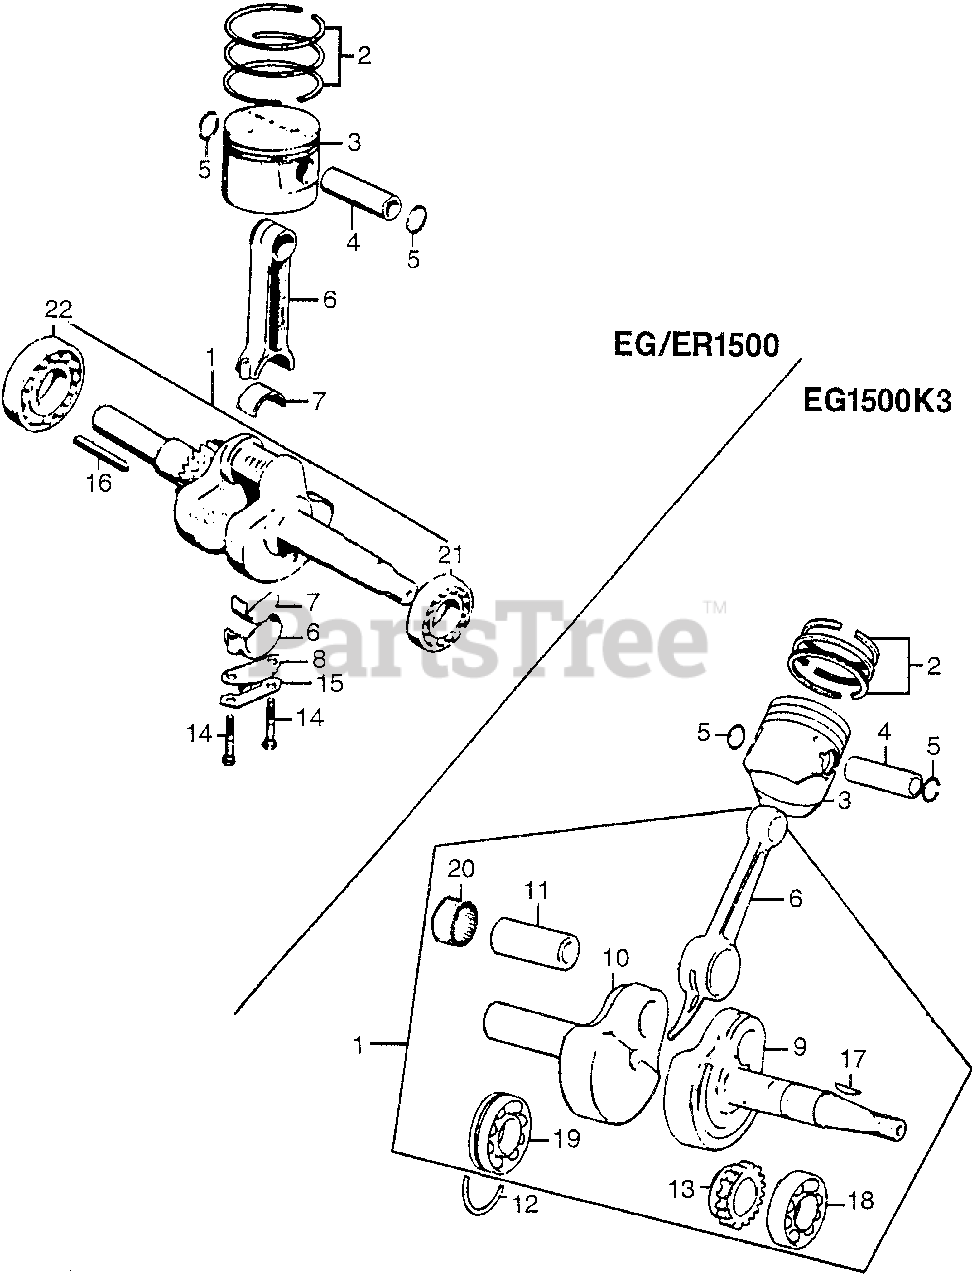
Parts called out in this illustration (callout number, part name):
1	CRANKSHAFT ASSY. (NOT AVAILABLE)
2	RING SET, PISTON (STD)
2	RING SET, PISTON (OS 0.25)
2	RING SET, PISTON (OS 0.50)
2	RING SET, PISTON (0.75)
3	PISTON (STD)
3	PISTON (OS 0.25)
3	PISTON (OS 0.50)
3	PISTON (0.75)
4	PIN, PISTON
5	CLIP, PISTON PIN (18MM)
6	ROD, CONNECTING (NOT AVAILABLE)
7	BEARING, CONNECTING ROD (STD) (NOT AVAILABLE)
7	BEARING, CONNECTING ROD (0.25)
7	BEARING, CONNECTING ROD (0.50)
7	ROD, BEARING
8	OIL DIPPER
14	BOLT, CONNECTING ROD
15	WASHER, CONNECTING ROD LOCK
16	KEY (7X7X33)
21	BEARING, RADIAL BALL (6205)
22	BEARING, RADIAL BALL (6206)
